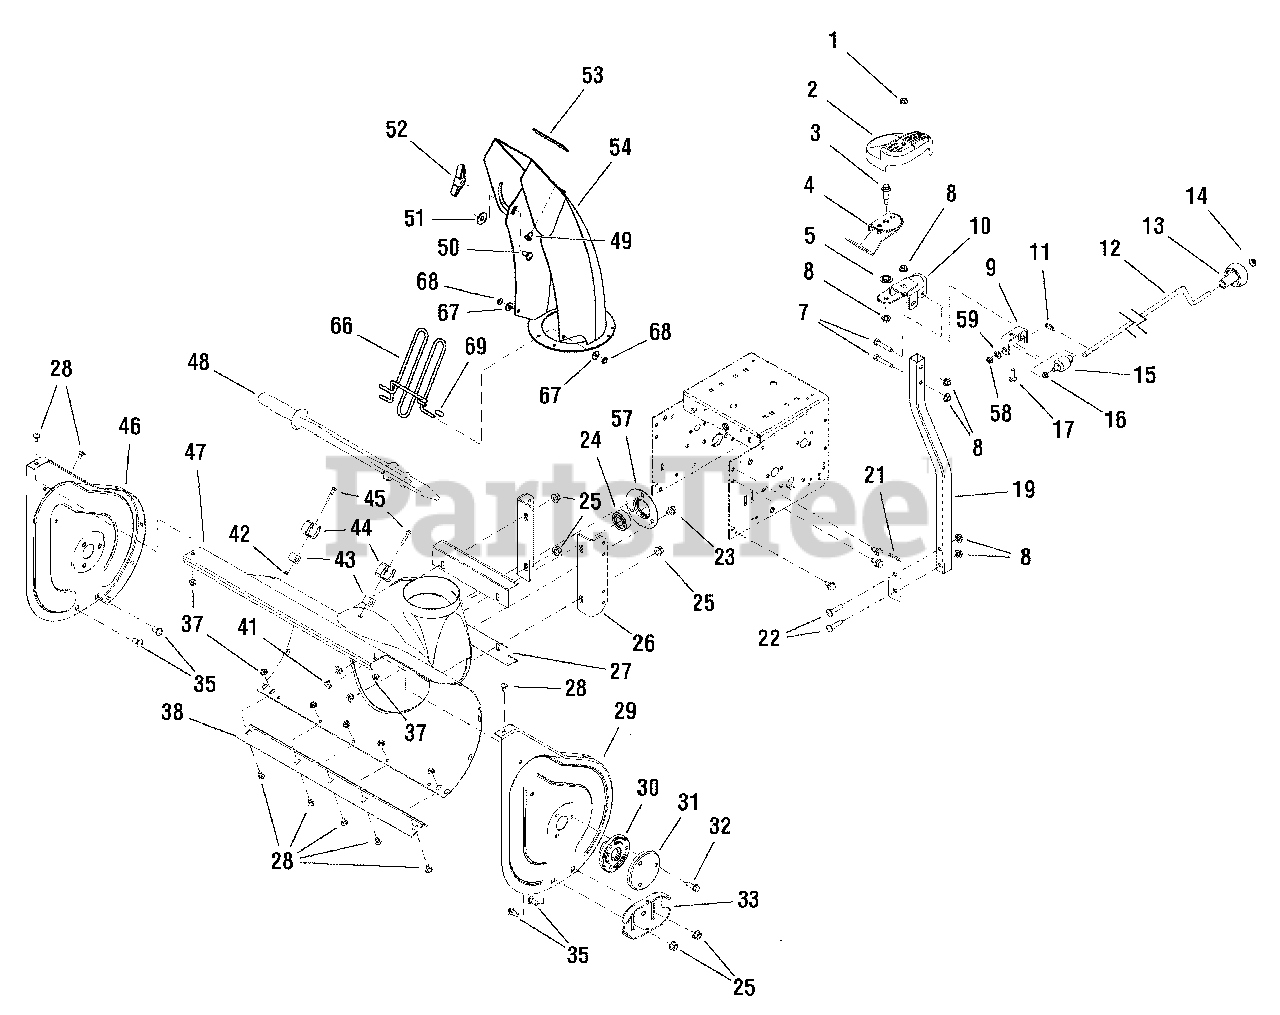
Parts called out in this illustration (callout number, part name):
1	NUT, Hex Flange 5/16-18 Two Way Lock
2	COVER, Gears
3	BOLT, Shoulder 5/16-18 G5
4	GEAR & SUPPORT ASSEMBLY, Chute
5	WASHER, Powdered Metal
7	CAPSCREW, Hex Head 5/16-18 x 1-3/4 G5
8	NUT, Hex KEPS 5/16-18 Conical Washer
9	SUPPORT, Worm "U" 10GA
10	SUPPORT, Gear & Chute 10GA
11	PIN, Hair Chute Gear
12	ROD, Chute Control E-Coat
13	KNOB, Spinner
14	NUT, Push Pal 3/8 Diameter Stud Capped
15	WORM, Chute L.H.
17	CARRIAGE BOLT, 5/16-18 x 1 G5
21	SUPPORT, Tube 10GA
22	CARRIAGE BOLT, 5/16-18 x 1-1/2 G5
23	SCREW, Hex Whiz Lock Flange 5/16-18 x 1/2
24	BEARING, Ball
25	NUT, Hex Flange 3/8-16 ESNA
26	BRACKET, Housing 12GA
27	ANGLE, Fill Strip
28	CARRIAGE BOLT, 1/4-20 x 1/2 G5
29	PLATE, End L.H.
30	HOUSING, Auger Bearing
31	CAP, Bearing
32	SCREW, Hex Washer Head Taptite 5/16-18 x 1
33	SKID, Shoe Reversible
35	CARRIAGE BOLT, 3/8-16 x 3/4 G5
37	NUT, Hex Flange 1/4-20 Whiz Lock Large
38	BLADE, Scraper 24"
41	RETAINER, Nut, 5/16-18
42	NUT, Hex Lock 10-24 w/Nylon Insert
43	BLOCK, Universal Pivot
44	CLIP, Retainer
45	SCREW, Hex Washer Head Slot #10C x 1-1/4 G2
46	PLATE, End R.H. 14GA
47	WRAPPER ASSEMBLY, 24" Auger
48	STICK, Cleanout w/Brush
49	SCREW, Phillips Head Taptite, Torx 5/16C x 1/2
50	CARRIAGE BOLT, 5/16-18 x 3/4
52	WINGNUT, 5/16-18
53	DECAL, Hinge
54	CHUTE & DEFLECTOR ASSEMBLY
57	RETAINER, Bearing
58	NUT, Hex Lock Jam ESNA Lite 3/8-24
59	WASHER, Cup
66	GUARD, Chute
67	WASHER, Nylon
68	NUT, Push 1/4
69	CAP, Wire 1/4
